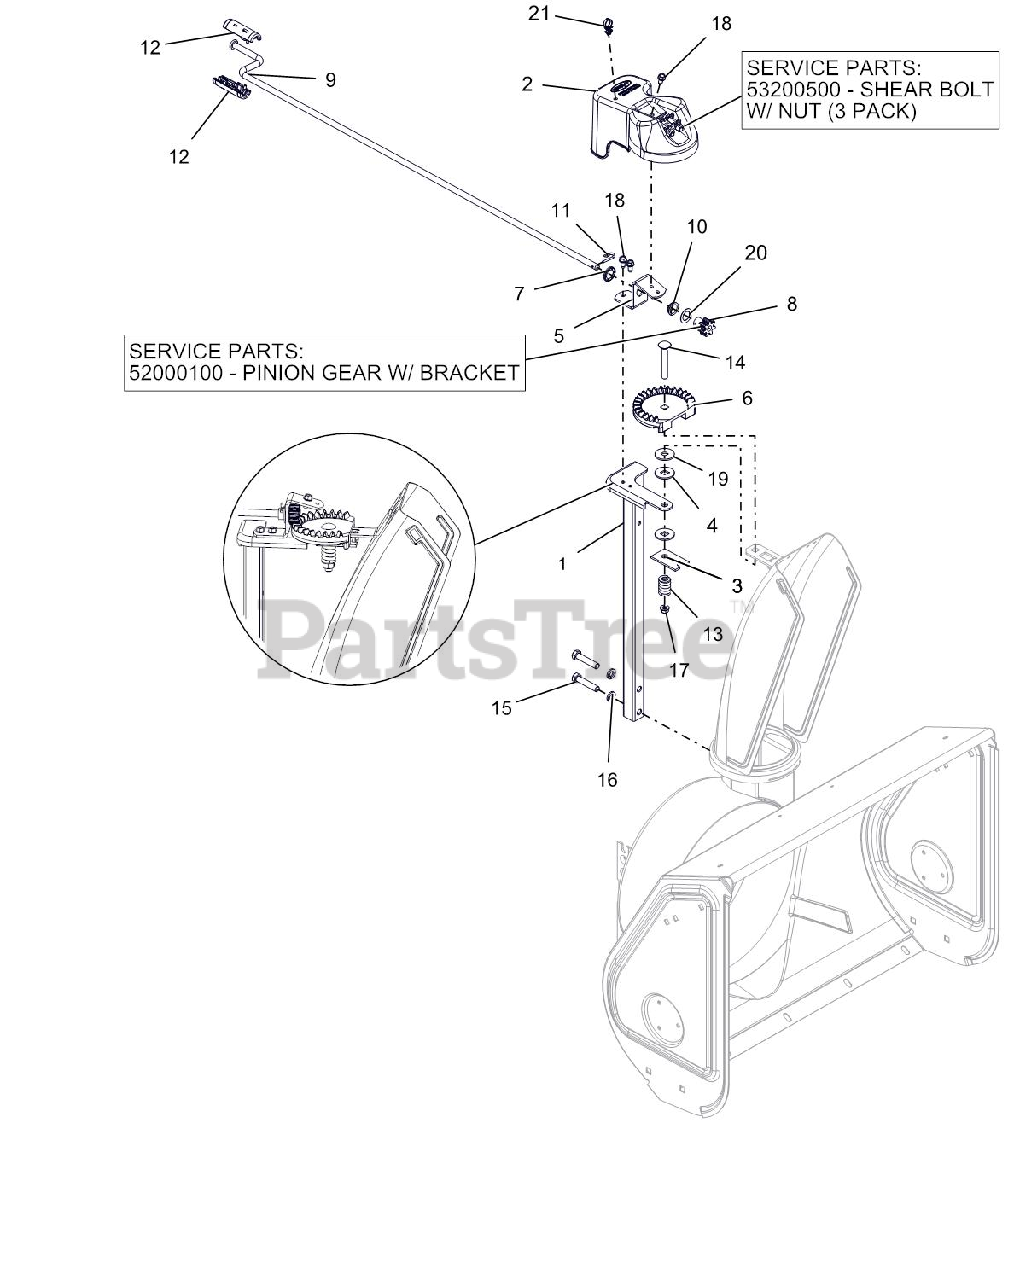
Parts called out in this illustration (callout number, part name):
1	CHUTE PEDESTAL, TALL COMPACT
2	SHEAR BOLT WITH NUT
2	GEAR COVER ASSY SM SHEAR BOLT
3	PLATE, FRICTION
4	FRICTION WASHER
5	BRACKET, PINION GEAR
6	CHUTE GEAR
7	PUSHNUT .625
8	PINION GEAR W/BRACKET
8	PINION GEAR - CHUTE
9	ROD, CHUTE CRANK, COMP&SNOTEK
10	BUSHING, POLYLINER-.63 SNAPIN
11	PIN, SPRING CLIP
12	KNOB,CRANK-SNAP COMPACT-GRAY
13	SG-COMP .187X.56X1.62
14	@BLT-RDHDSQNK .38-16X2.50 G5YZ
15	@BLT-HEX .38-16X1.75 GR5 YWZC
16	@WSHR-LK .38X.094 REG YWZC
17	@NUT-LK-TOP-FLG .25-20 YWZC
18	SCR-TAP .25-20X.50 HWH TR YWZ
19	@WSHR-FL-STL .406X1.25X.10 ZC
20	WSHR-THRST .625 X 1.0 X .03
21	CLIP, CABLE GUIDE
